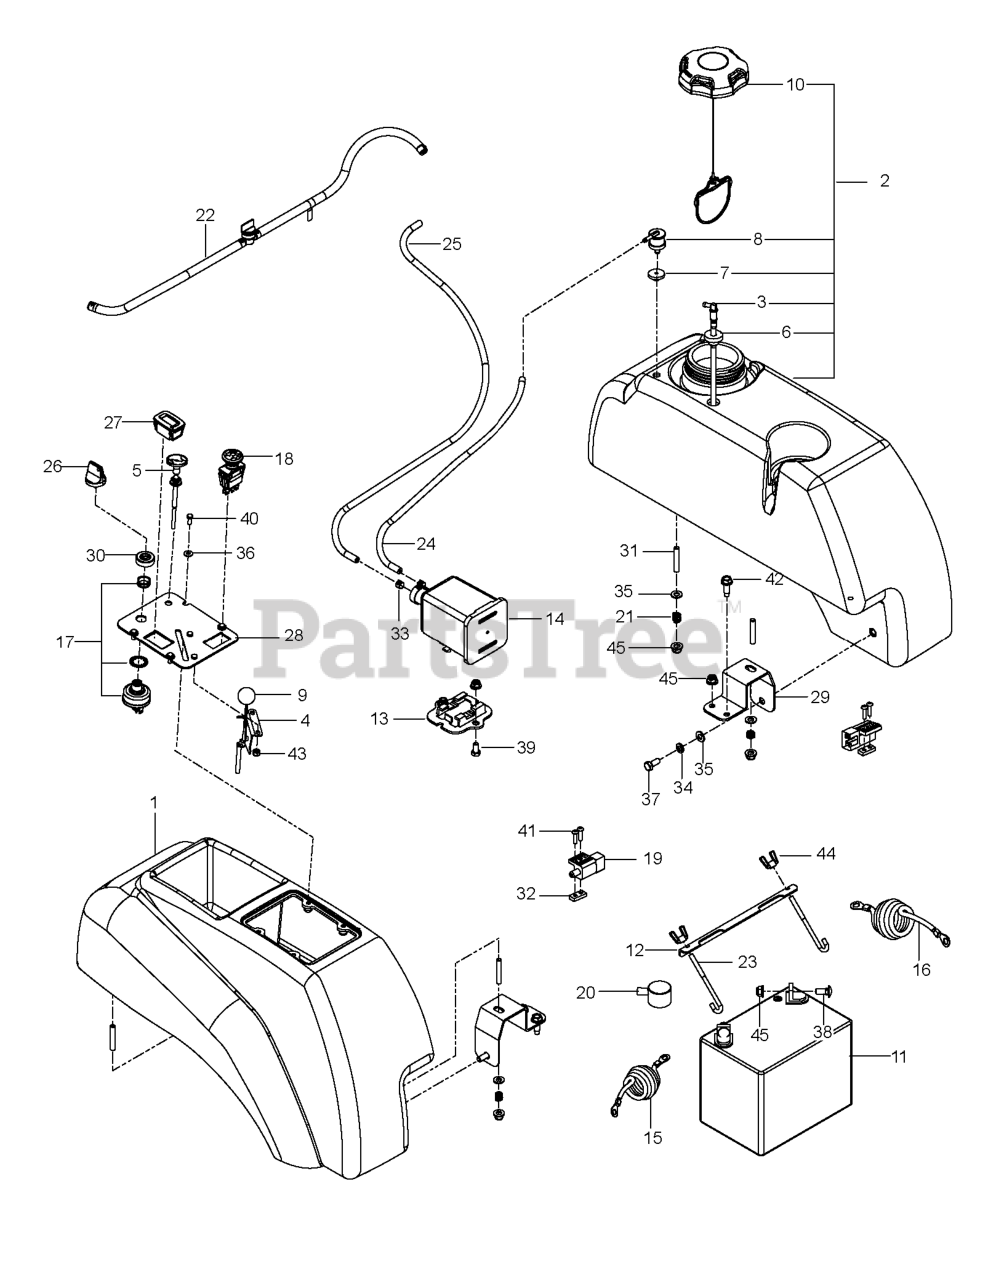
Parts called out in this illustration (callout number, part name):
1	FENDER CONSOLE
2	FUEL.TANK.ASSY.LH.MZ.GRY
3	FITTING, FUEL
4	THROTTLE CABLE
5	CABLE, CHOKE, 38
6	RUBBER GROMMET
7	GROMMET, CHECK VALVE
8	VALVE.FUEL.CHECK
9	KNOB.ROUND.BALL.BLACK
10	CAP, FUEL
11	BATTERY, 12 V 330 AMP
12	BRACKET, BATTERY MOUNT
13	BRACKET, CANISTER
14	CANNISTER, CARBON
15	CABLE.BATT.SOLENOID.MZ.RED.25"
16	CABLE.GROUND.BATT.MZ.BLACK.39"
17	SWITCH, IGNITION, INDAK
18	RP SWITCH.PTO.TERMINAL.STD.RED
19	SWITCH INTERLOCKT
20	COVER.TERMINAL.BATTERY
22	FUEL.HOSE.SHUT.OFF.ASM.10".10"
24	HOSE.3/16".VAPOR.LINE.27"LGTH
25	HOSE.3/16".VAPOR.LINE.64"LGTH
26	KEY, IGNITION
27	GUAGE.SRVCMNDR.HRMTR.
28	PLATE, CONSOLE, BLK
29	SUPPORT, TANK, BLK
30	CAP IGNITION NUT
31	STUD, 5/16C
32	PLATE NUT ZTR
33	CLAMP, HOSE
34	WASH.5/16.SLW.ZD
35	WASHER
37	BOLT.FIN.HEX.5/16-18X3/4
38	RP BOLT 5/16-18 X3/4 ZN/YEL GR
39	HCS 5/16-18 X 5/8 GR 5 ZD
40	HCS #10-24 X 1/2
41	SCR #10-24 X .75 SKT HD BLK
42	SCREW
43	NUT 10-24 NYLOC
44	WING NUT 1/4
45	5/16-18 NYLOC FLANGE NUT
